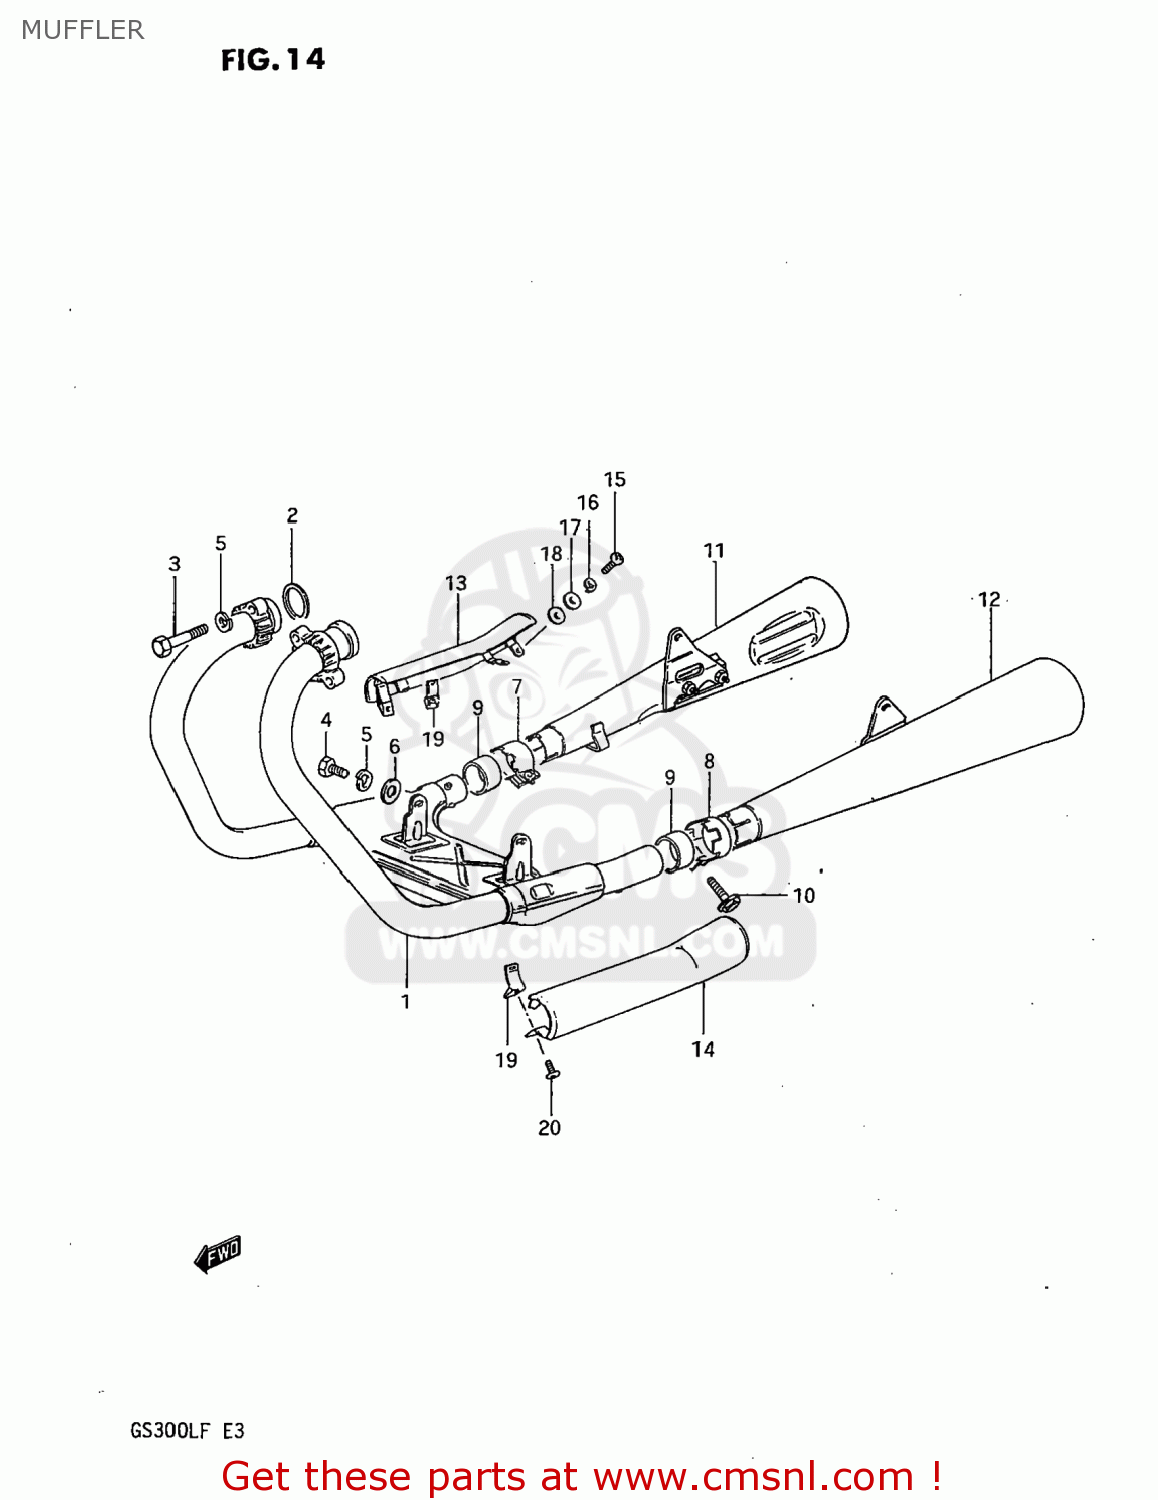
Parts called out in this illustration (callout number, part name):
1	PIPE,EXHAUST
2	GASKET,EXHAUST PIPE (NAS)
3	BOLT 8X40
4	BOLT
5	LOCK WASHER
6	WASHER
7	CLAMP,MUFFLER CONNECTOR,R
8	CLAMP,MUFFLER CONNECTOR,L
9	CONNECTOR,MUFFLER
10	BOLT
11	MUFFLER ASSEMBLY,RIGHT
12	MUFFLER ASSEMBLY,LEFT
13	COVER,MUFFLER,RIGHT
14	COVER,MUFFLER
15	SCREW 6X12
16	LOCK WASHER
17	WASHER
18	GASKET 6.2X12X1.5 (MCA)
19	CLAMP,MUFFLER COVER
20	SCREW
